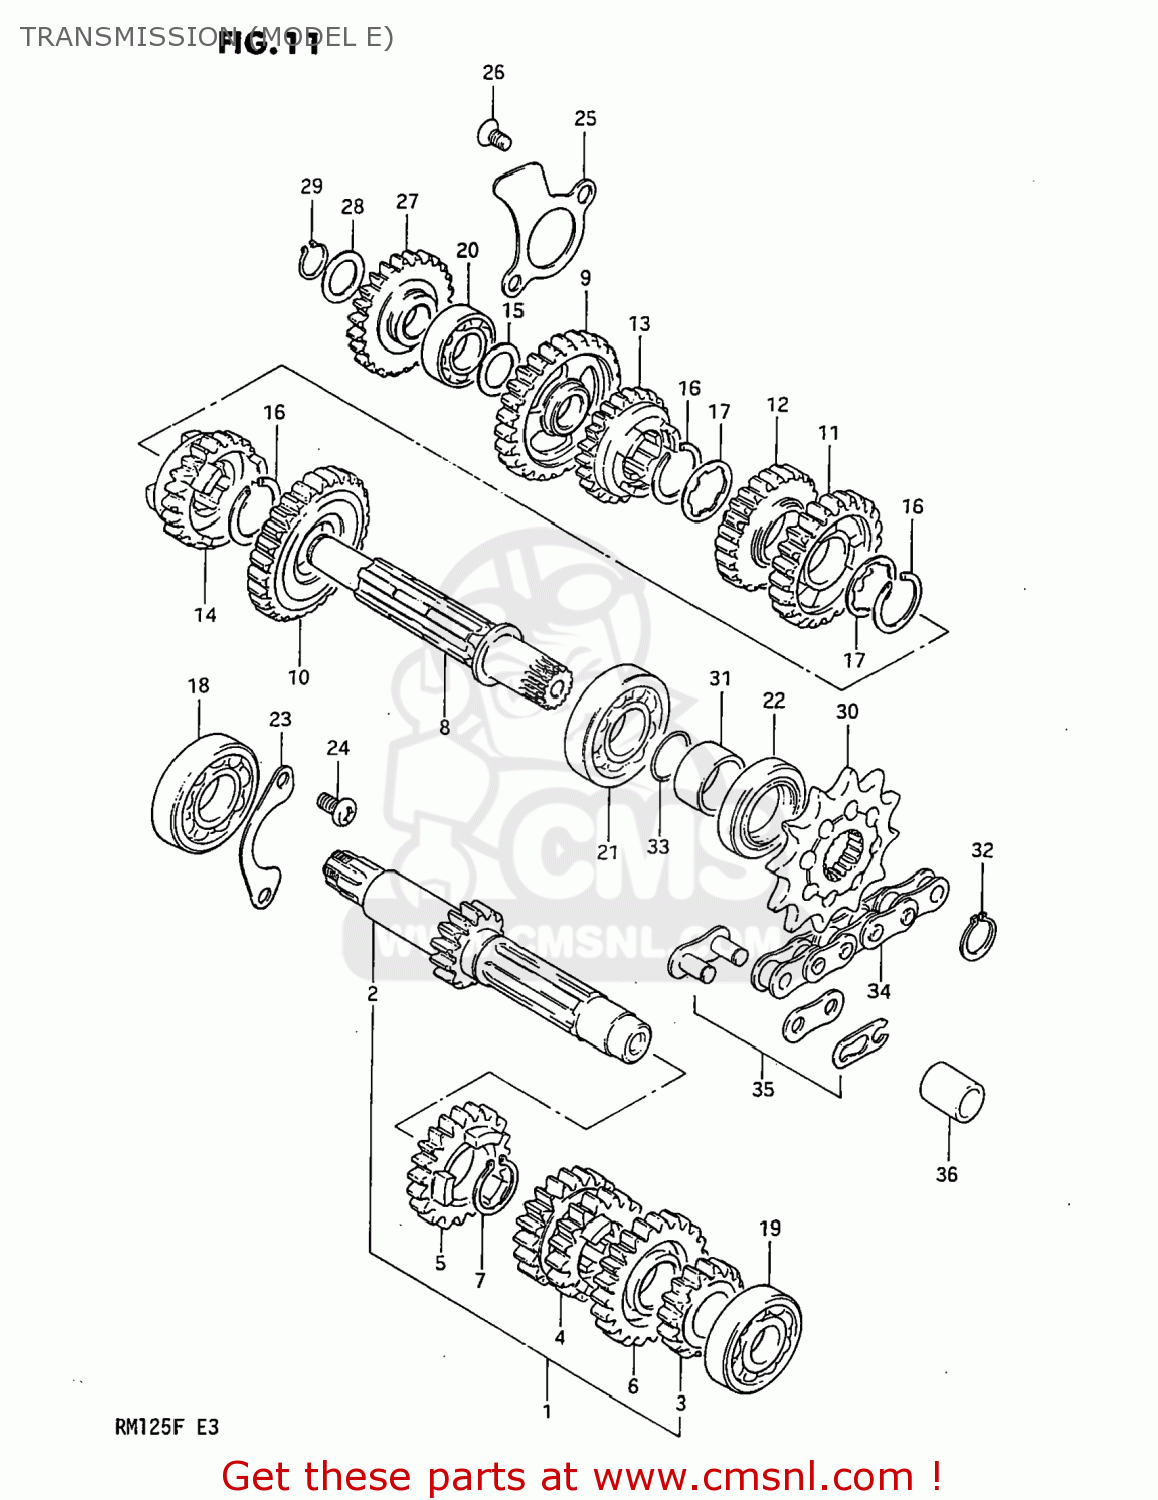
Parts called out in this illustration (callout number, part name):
1	COUNTER SHAFT ASSEMBLY
2	SHAFT,COUNTER
3	GEAR,2ND DRIVE
4	GEAR,THIRD & FOURTH DRIVE
5	GEAR,FIFTH DRIVE
6	GEAR,6TH DRIVE(NT:23)
7	CIRCLIP
8	SHAFT,DRIVE
9	GEAR,FIRST DRIVEN (NT:31)
10	GEAR,SECOND DRIVEN
11	GEAR,THIRD DRIVEN (NT:24)
12	GEAR,FOURTH DRIVEN (NT:25)
13	GEAR,FIFTH DRIVEN (NT:23)
14	GEAR,SIXTH DRIVEN (NT:22)
15	WASHER,THRUST
16	CIRCLIP
17	WASHER,LOCK
18	BEARING
19	BEARING
20	BEARING
21	BEARING(20X47X14)
22	SEAL,OIL(25X40X7)
23	RETAINER,CNTR SHAFT BEARING
24	SCREW 6X12
25	RETAINER,DRIVESHAFT
26	SCREW
27	GEAR,KICK STARTER IDLE
28	WASHER,THRUST
29	CIRCLIP,15MM
30	SPROCKET,ENGINE
31	SPACER(20X25X12.5)
32	CIRCLIP
33	O RING(D:1,ID:19.5)
34	CHAIN ASSEMBLY,DRIVE
35	JOINT ASSEMBLY,CHAIN
36	CUSHION 12X20X20
